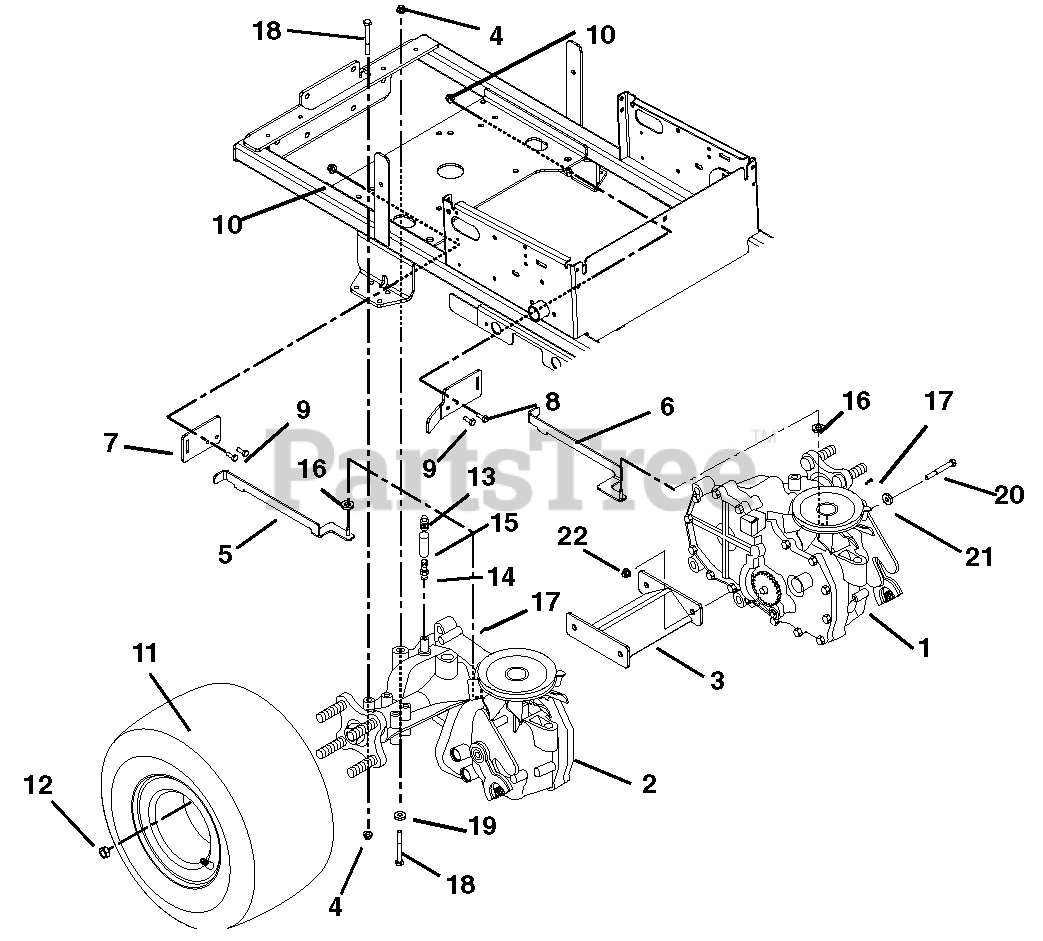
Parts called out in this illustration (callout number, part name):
1	EZT, Left Hand Transaxle-Hydrogear (102, 104, 132)
2	EZT, Right Hand Transaxle-Hydrogear (102, 104, 132)
3	Weldment, Transaxle Support
4	Nut 5/16-18 Flange Nyloc
5	Weldment, Dump Valve (RH)
6	Weldment, Dump Valve (LH)
7	Bracket, Dump Valve
8	Bracket, Dump Valve/Clutch Stop (104, 132)
9	Bolt-Hex .25-20 x .75 Grade 5
10	Nut, Locking Nylon .250-20
11	Assembly, Tire Wheel 18 x 8.5-8 CTR (102, 104, 132)
12	Nut, Lug .50-20
13	Cap, Vent .50
14	Fitting, Straight .50
15	Hose, Vent
16	Washer-Flat-Steel .265 x .50 x .087
17	Pin-Hair-Internal .06 x .18 x .77
18	Bolt, Hex .31-18 x 2.75
19	Washer, Flat Steel .328 x .87 x .179
20	Bolt, Hex .38-16 x 2.50 Grade 5
21	Washer, Flat Steel .406 x 1.00 x .188
22	Nut, .38-16 Nyloc Flange
